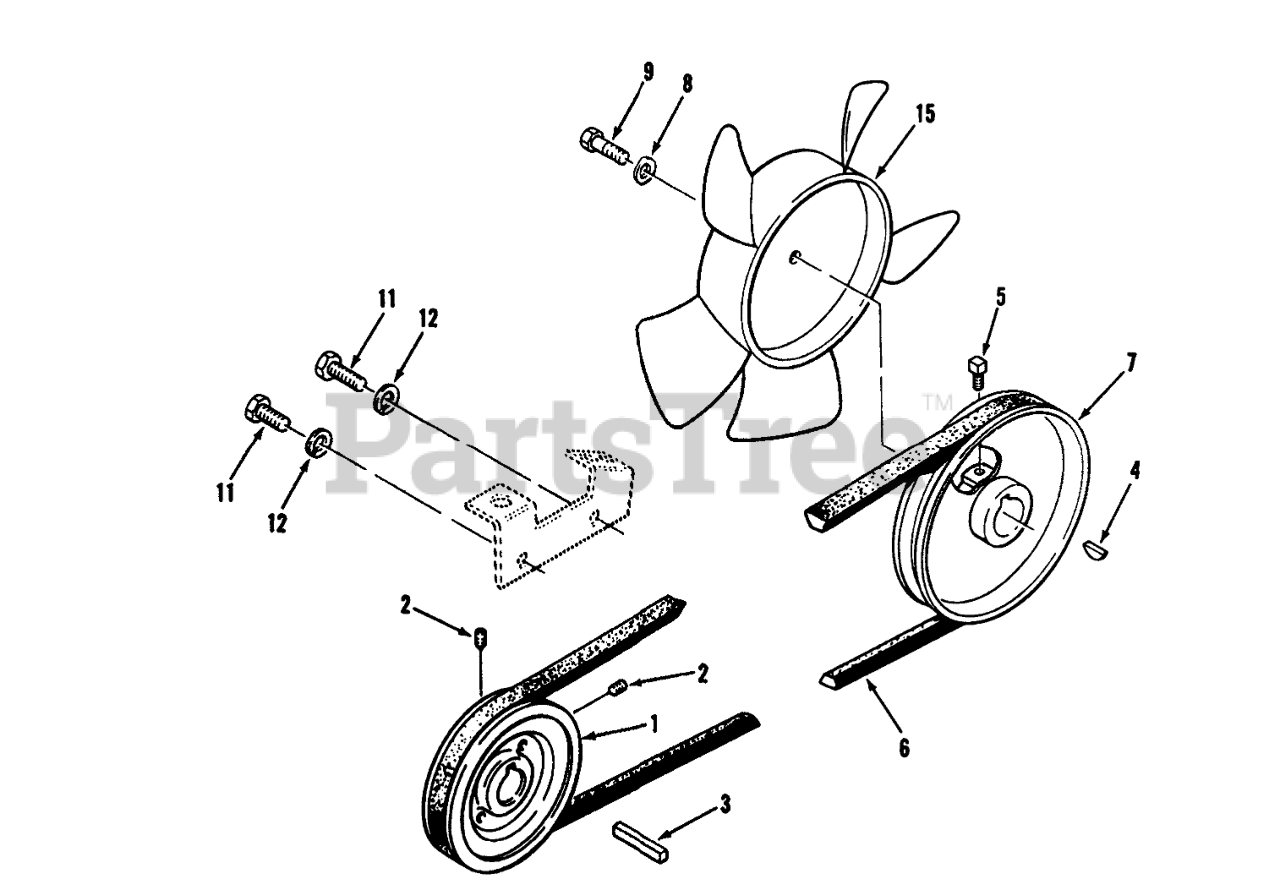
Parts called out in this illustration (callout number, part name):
1	PULLEY
2	SCREW-SET, HSH
4	KEY-WOODRUFF
5	SCREW-SQH
6	BELT-V
7	PULLEY
8	WASHER
9	SCREW-HH
11	SCREW-HH, LOCK
12	WASHER-PLAIN
15	NYLON FAN-L-CW
